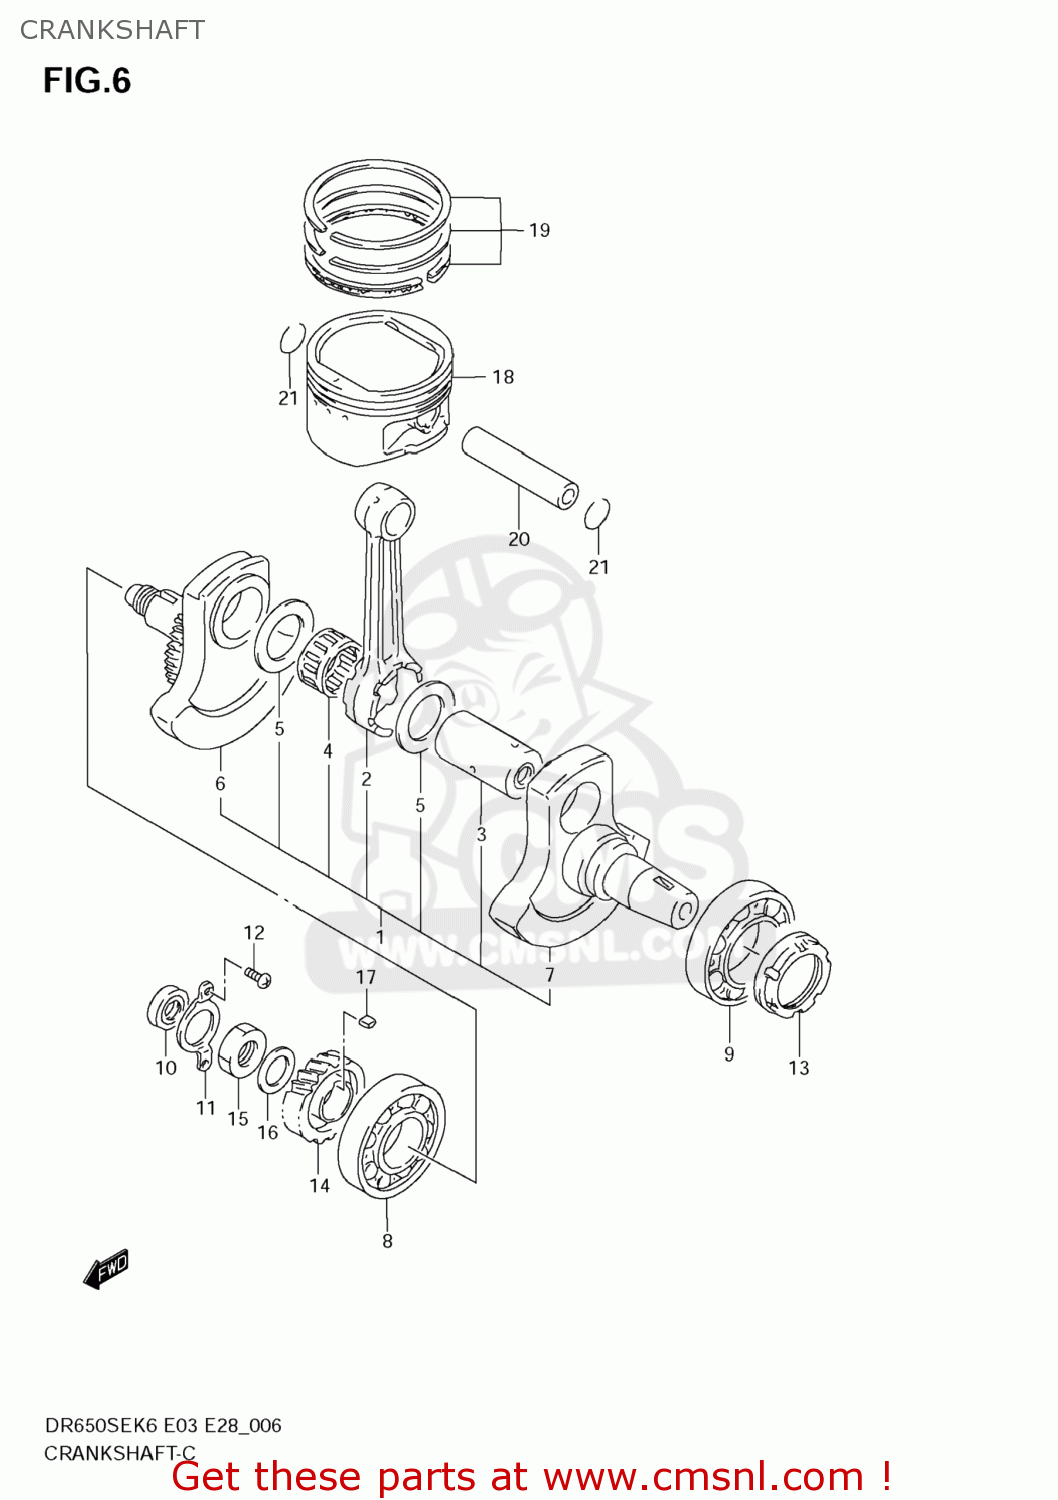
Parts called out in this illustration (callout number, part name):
1	CRANKSHAFT SET
2	CONNECTING ROD
3	PIN,CRANK
4	BEARING(37X47X25)
5	WASHER(37X55X1)
6	CRANKSHAFT SET,R
7	CRANKSHAFT,L
8	BEARING(40X80X18)
9	BEARING(45X85X19)
10	SEAL,OIL(16X30X6)
11	RETAINER,CRANKSHAFT BEARING,R
12	SCREW
13	NUT,CRANKSHAFT BRG,L
14	GEAR,PRIMARY DRIVE(NT:28)
15	NUT
16	WASHER
17	KEY
18	PISTON (100.00MM)
19	RING SET,PISTON
20	PIN,PISTON
21	CIRCLIP
